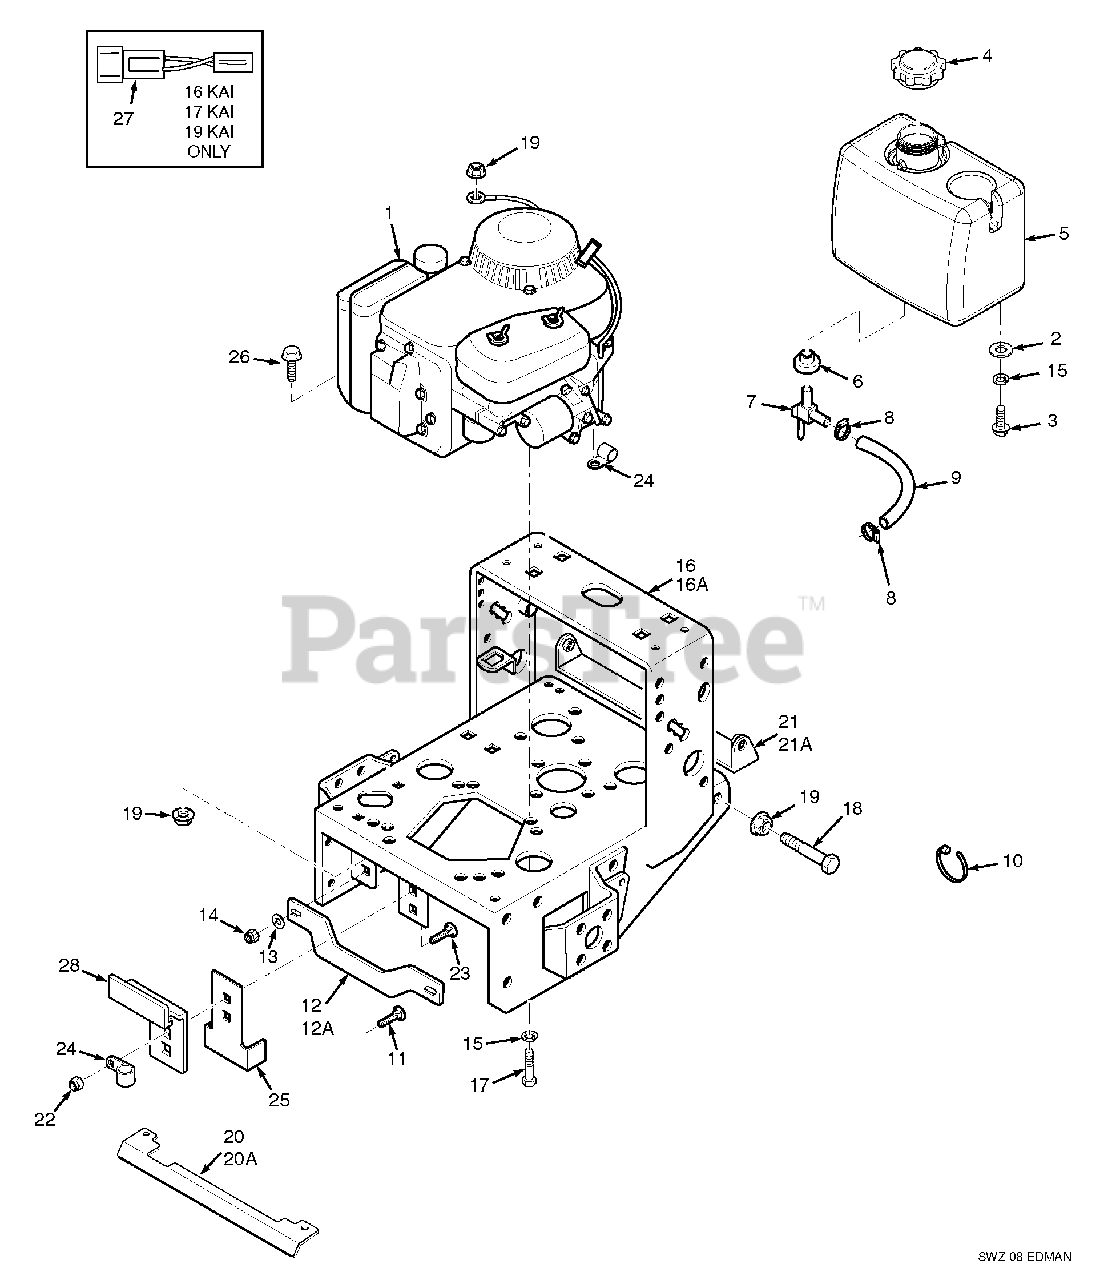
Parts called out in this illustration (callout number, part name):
1	Engine, 16HP Kawasaki (Spec FH480V-BS24-R)
1	Engine, 17HP Kawasaki (Spec FH541V-BS38-R)
1	Engine, 19HP Kawasaki (Spec FH580V-BS34-R)
2	Flatwasher, 5/16 - .375 x .875 x .083
3	Capscrew, 5/16-18 x 1" Hex Head
4	Cap, Fuel Tank
5	Fuel Tanks Assembly
6	Bushing
7	Valve, Fuel Shut Off w/Screen
8	Clamp, Fuel Hose
9	Fuel Hose, 1/4" ID x 18"
10	Cable Tie
11	Bolt, Carriage 3/8-16 x 1-1/4"
12	Brace, 16" Small Frame
12A	Brace, 20" Large Frame
13	Flatwasher, .391 x .938 x .105
14	Nut, 3/8-16 Elastic Stop
15	Lockwasher, 5/16"
16	Engine Deck, 16" Wide w/Decals
16A	Engine Deck, 20" Wide w/Decals
17	Bolt, 5/16-18 x 1"Serrated Flange
18	Bolt, 5/16-18 x 2" Hex Head
19	Nut, 5/16-18 Serr. Flange
20	Heatshield, 16" Small Frame
20A	Heatshield, 20" Large Frame
21	Pulley Guard, 16" Small Frame
21A	Pulley Guard, 20" Large Frame
22	Nut, 5/16-18 Elastic Stop
23	Bolt, Carriage 5/16-18 x 1"
25	Clutch Bracket
26	Capscrew, 5/16-18 x 1-1/2" Serr. Flange
27	Wire Harness Adapter
28	Plate, Clutch Bracket
